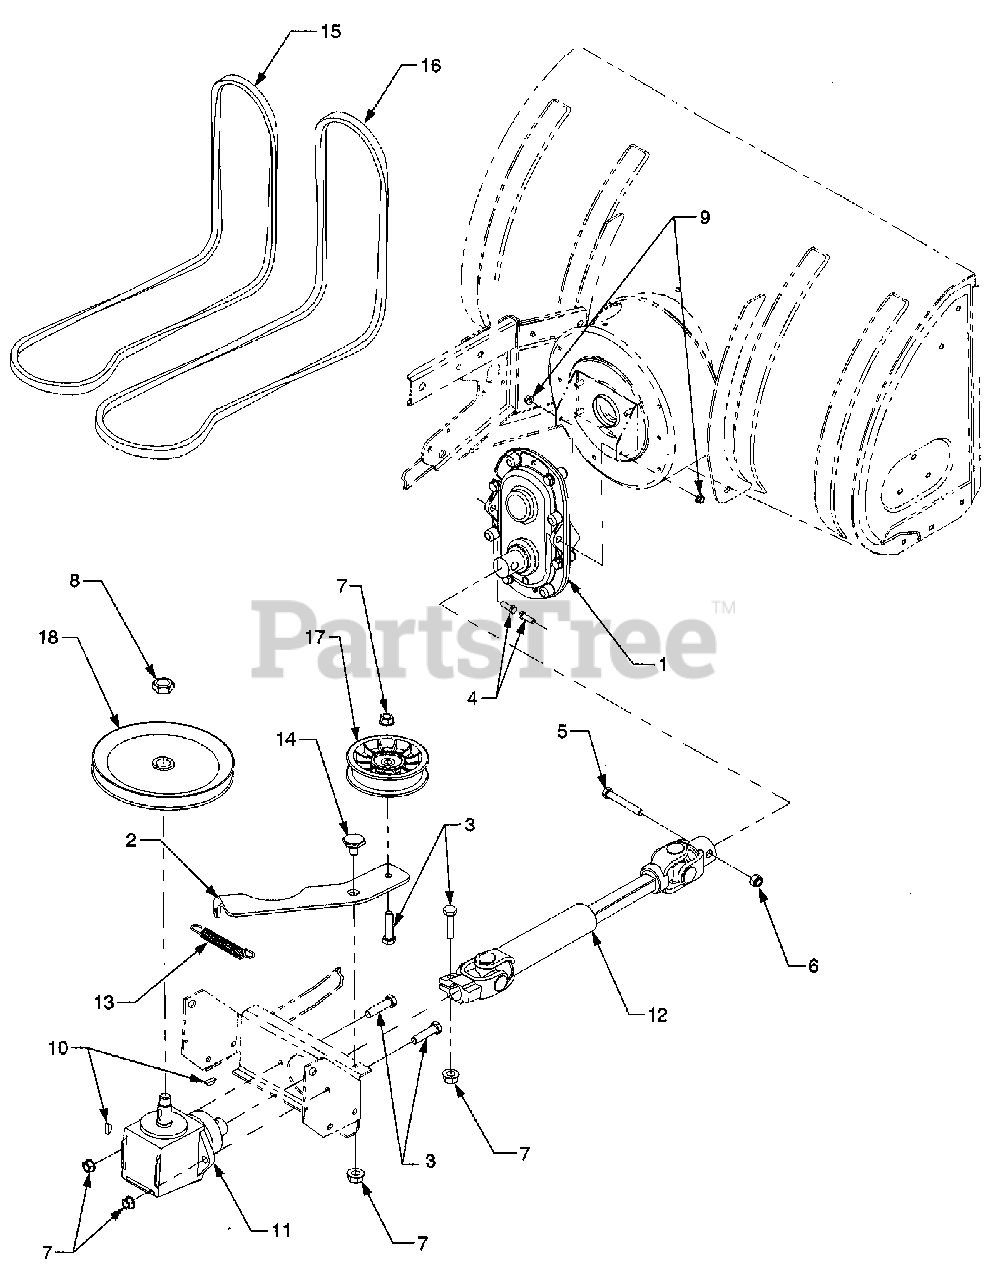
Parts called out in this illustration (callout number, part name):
1	Box Assemlby
2	Arm, Idler Pivot
3	Screw, Hex Cap 3/8-16 x 1.5 GR5
4	Screw, Hex Cap 1/4-20 x .75 GR5
5	Screw, Hex Cap 5/16-24 x 2.0 GR5
6	Nut, Hex, 5/16-24
7	Nut, Hex Flange Lock, 3/8-16
8	Nut, Hex Center Lock, 5/8-18
9	Nut, Hex Nylon Insert Lock,1/4-20
10	Key, Hi-Pro, 3/16 x 3/4
11	Box, Gear
12	Shaft, Drive
13	Spring, Extension
14	Bolt, Shoulder, .625 Dia x .21
15	Belt PTO, A-Section x 76.1
16	Belt, PTO, B-Section x 78.3
17	Pulley, Flat Idler
